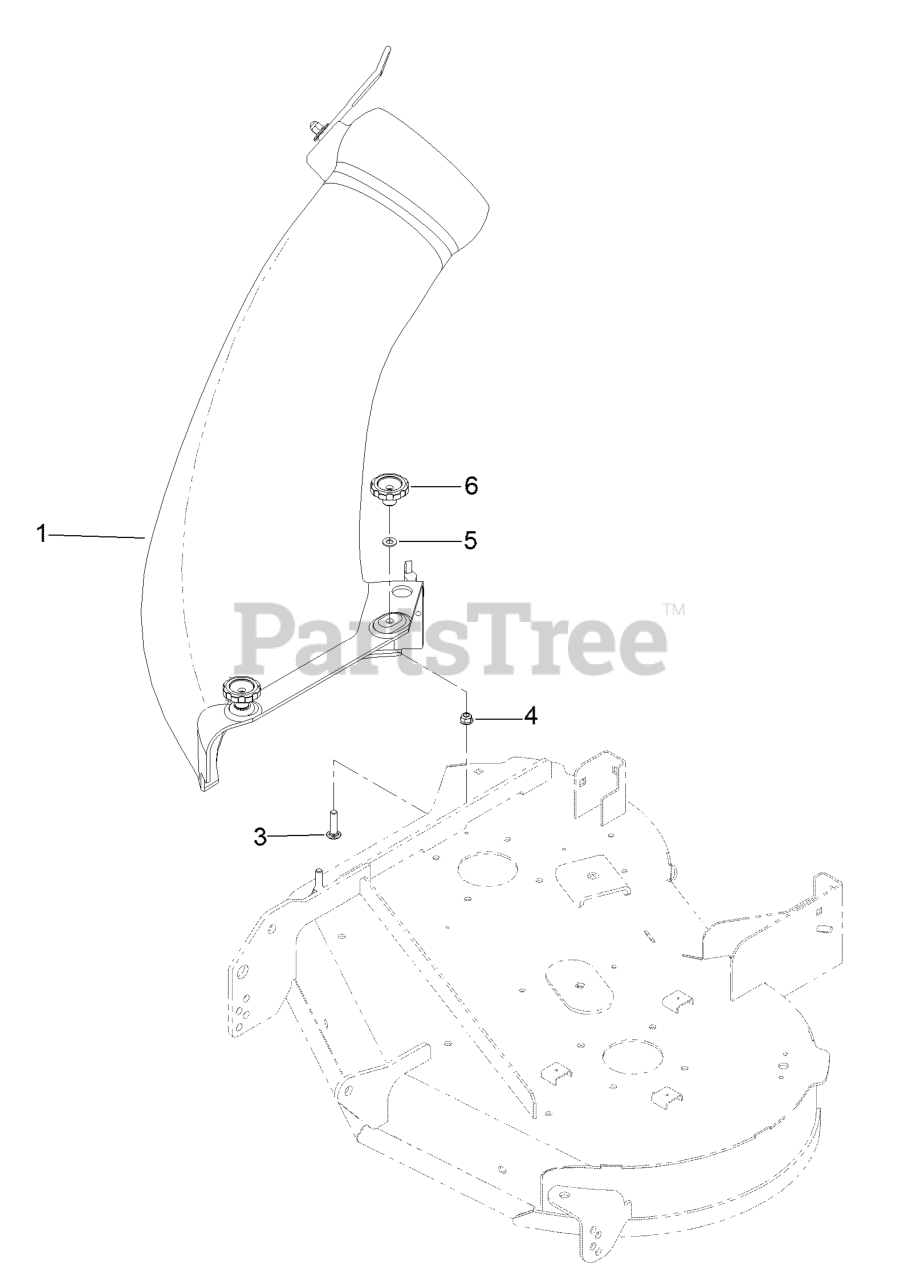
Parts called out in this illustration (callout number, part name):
1	34 INCH CHUTE ASM
3	SCREW-CARR
4	NUT-HF, NI
5	WASHER-PLAIN
